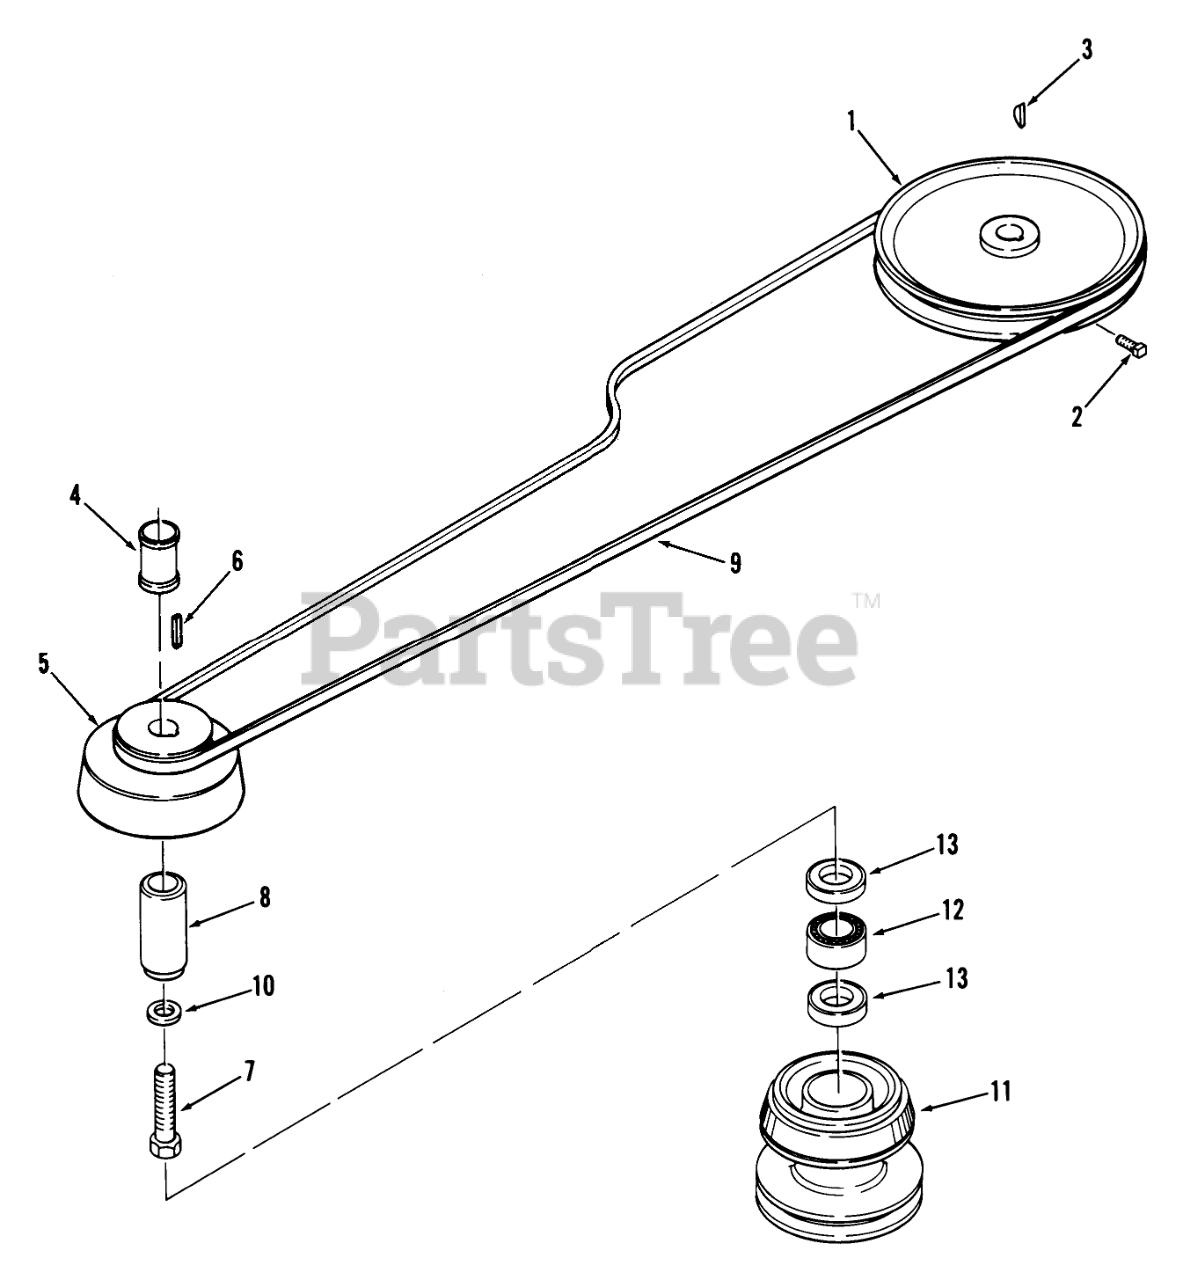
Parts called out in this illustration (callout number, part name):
1	PULLEY-TRANSMISSION
2	Set Screw
3	HARD HI PRO KEY
4	TUBE SPACER
5	Pulley-Engine
7	HEX HD CAP SCREW
8	RACE BEARING
9	V-BELT
10	WASHER
11	Assy Pulley Mwr Dr
12	BRG-NEEDLE OPEN END
13	SEAL-OIL
